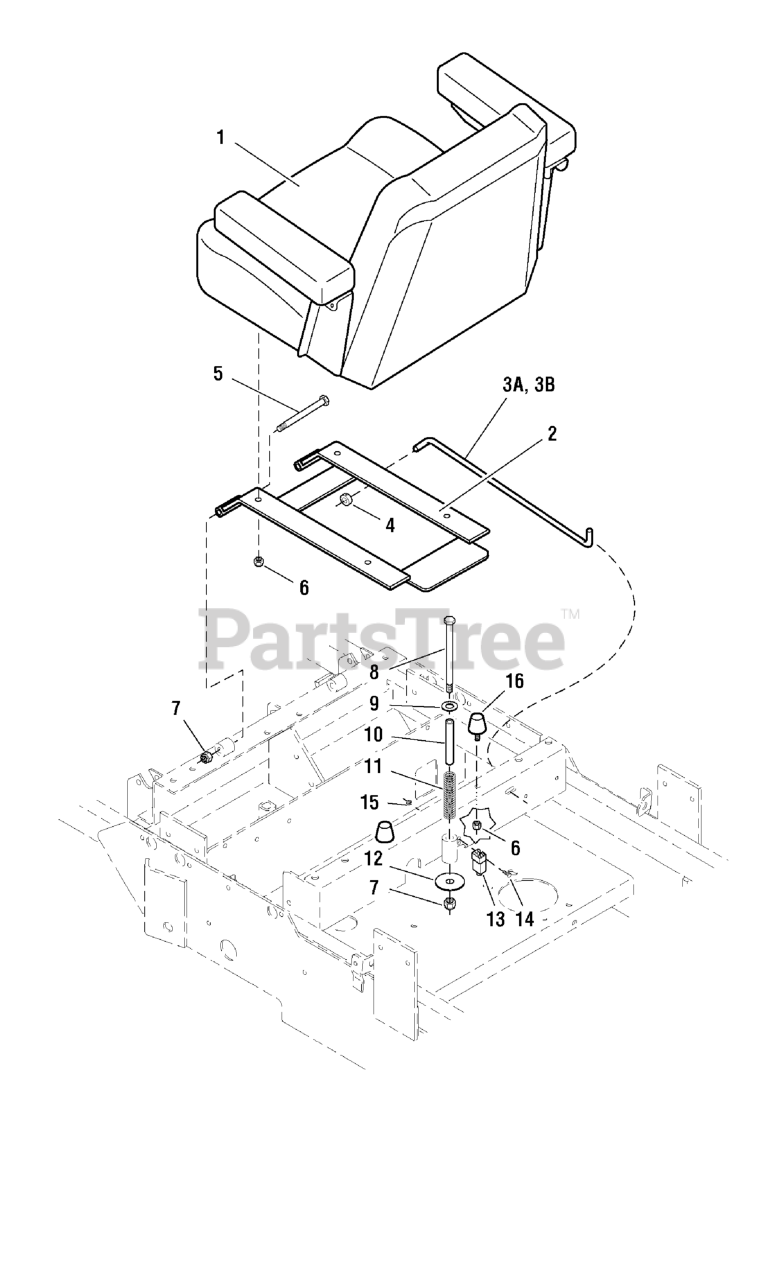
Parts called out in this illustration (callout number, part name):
1	SEAT, Deluxe, Gray, Complete
1	SEAT Bottom Cover
1	SEAT Back Cover
1	ARM REST SET
1	ARM REST PADS
1	SEAT ADJUSTER RAILS (set of 2)
2	WELD, SEAT MOUNT
3A	SEAT STOP ROD
3B	SEAT STOP ROD
4	COLLAR, 5/16" Set
5	BOLT, 3/8-16 X 4" GD5 CZ
6	NUT, 5/16-18 Hex Nylon Lock
7	NUT, 3/8-16 HEX NYLON LOCK
8	BOLT, 3/8-16 X 6" GD5 CZ
9	WASHER, 3/8 SAE
10	SPACER, .38 x .50 x 5.06
11	SPRING, Compression
12	WASHER, 3/8 x 2
13	SWITCH, Plunger, NO/NC
14	SCREW, #10-24 X 1 RS, CZ
15	NUT, #10-24 Hex
16	RUBBER BUMPER
17	SPRING, EXTENSION, SEAT ADJUSTMENT (YEL OR BLK)
